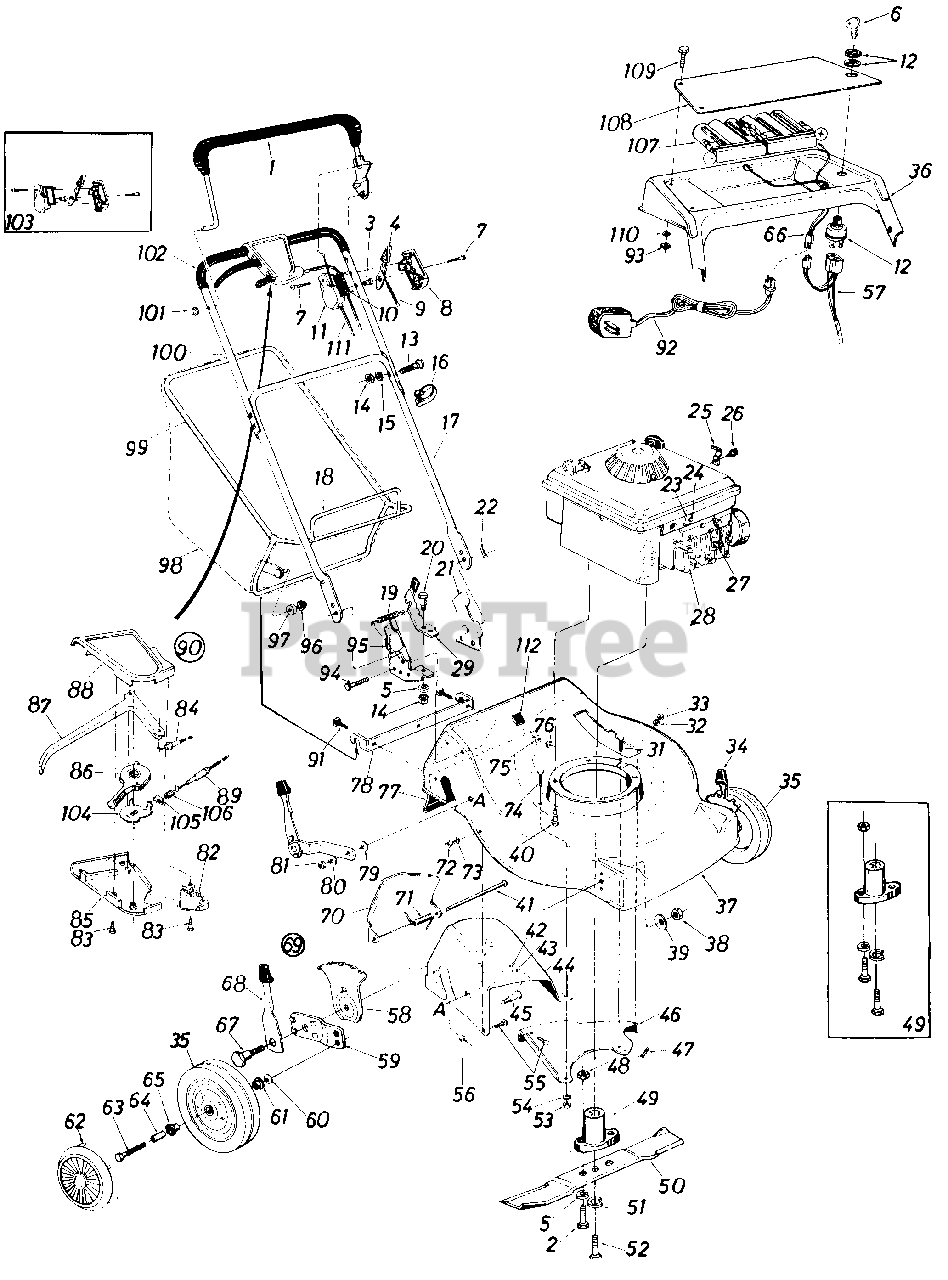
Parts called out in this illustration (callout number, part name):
1	L.H. Bail Ass'y.
2	Hex Bolt 5/16-24 x 1.00" Lg. (Grade 5)
3	Control Disc Pin
4	Throttle Control Lever
5	L-Wash. 5/16" I.D.
6	Ignition Key
7	Truss Mach. Hi-B Tap Scr. #12 x 1.50" Lg.
8	Control Panel Half
9	Throttle Control Wire- 58" Lg.
10	Control Label
11	Clutch Panel Half
12	Ignition Switch
13	Curved Carr. Bolt 5/16-18 x 1.75" Lg.
14	Hex Nut 5/16-18 Thd.
15	L-Wash. 5/16" I.D.
16	Cable Tie
17	Lower Handle
20	Shld. Bolt .437" Dia. x .162
21	Handle Bracket Ass'y.-L.H.
22	Hairpin Cotter 5/16" Dia.
23	Casing Clamp
24	Hex Sems Scr. #10-32 x .62" Lg.
25	Cable Clip
26	Hex "B"-Tap Scr. #10 x .38" Lg.
27	Spark Plug Insulator
28	4 H.P. Engine B&S
29	L-Wash. 5/16" I.D.
31	Hex TT-Tap Scr. 1/4-20 x .75" Lg.
32	L-Wash. 1/4" I.D.
33	Hex Nut 1/4-20 Thd.
34	Height Adj. Ass'y.-L.H.
35	Front Wheel Ass'y. Comp. 8 x 1.75
36	Handle Panel
39	Bell-Wash. .39" I.D. x 1.38" O.D.
40	Hex Wash. Hd. TT-Tap Scr. 3/8-16 x 1.0" Lg.
41	Hinge Pin
42	Hex Nut 1/4-20 Thd.
43	L-Wash. 1/4" I.D.
44	Rear Chute-R.H.
45	Shld. Bolt .500" Dia. x .685"
46	Rear Baffle-L.H.
47	Carr. Bolt 1/4-20 x .50" Lg.
48	Hex Nut 5/16-24 Thd.
49	Blade Adapter Kit
50	22" Blade
51	L-Wash. 3/8" I.D. Heavy Duty
52	Hex Bolt 3/8-24 x 2.25" Lg. (Grade 5)
53	Hex Nut 1/4-20 Thd.
54	L-Wash. 1/4" I.D.
55	Carr. Bolt 1/4-20 x .50" Lg.
56	Hex Sems Nut 1/4 -20 Thd.
57	Wire Harness
58	Height Adj. Plate
59	Wheel Pivot Bar
60	Bell-Wash. .40" I.D. x .88" O.D.
61	Flg. Ball Brg. 3/8" I.D.
62	Plastic Hub Cap
63	Hex Bolt 3/8-16 x 1.75" Lg.
64	Spacer.375" I.D. x .505" O.D.
65	Flg. Ball Brg. 1/2" I.D.
66	Battery Pack Lead
67	Shld. Bolt .50" Dia. x .430
68	Spring Lever Ass'y. wlKnob
69	Height Adj. Ass'y.-R.H.
70	Chute Door
71	Torsion Spring
72	Hex Nut 1/4 -20 Thd.
73	L-Wash. 1/4" I.D.
74	Hex Bolt 1/4-20 x .88" Lg.
75	Fl-Wash. .285" I.D. x 1.25" O.D.
76	Hex Sems Nut 1/4-20 Thd.
77	Rear Flap
78	Grass Catcher Hitch Brkt.
79	Bell-Wash. .400" I.D. x 1.13" O.D.
80	Bell-Wash. .400" I.D. x .88" O.D.
81	Hex Jam Nut 3/8-16 Thd.
82	Cable Mounting Cap
83	Flat "C"-Sunk Hd. Tap Scr. #10 x .75" Lg.
84	S.P. Cable x 53" Lg.
85	3-Sp. S.P. Control- Lower Cover
86	Shimano 3-Sp. Shift Lever
87	Control Lever
88	3-Sp. S.P. Control- Upper Cover
89	Shimano 3-Sp. Sol id Shift Cable
90	Clutch Control Housing Comp.
91	Carr. Bolt 1/4-20 x .75" Lg.
92	Battery Charger
93	Hex Nut #8-32 Thd.
94	Hex Bolt 1/4-28 x .75" Lq.
95	Handle Bracket Ass'y.-R. H.
96	Push Nut 3/8" Rod
97	Plastic Roller
98	Grass Bag
99	Catcher Upper Frame
100	Upper Handle
101	Cap Speed Nut
103	Control Housing Comp.
104	Shimano 3-Sp. Shift Lever Brkt.
105	Shimano 3-Sp. Cable Spring Brkt.
106	Shimano 3-Sp. Cable Mounting Spring
107	Battery Pack
108	Battery Plate
109	Fl-Hd. Phil. Scr. #8-32 x .38" Lg.
110	External L-Wash. #8 I.D.
111	Clutch Control Cable 45" Lg.
